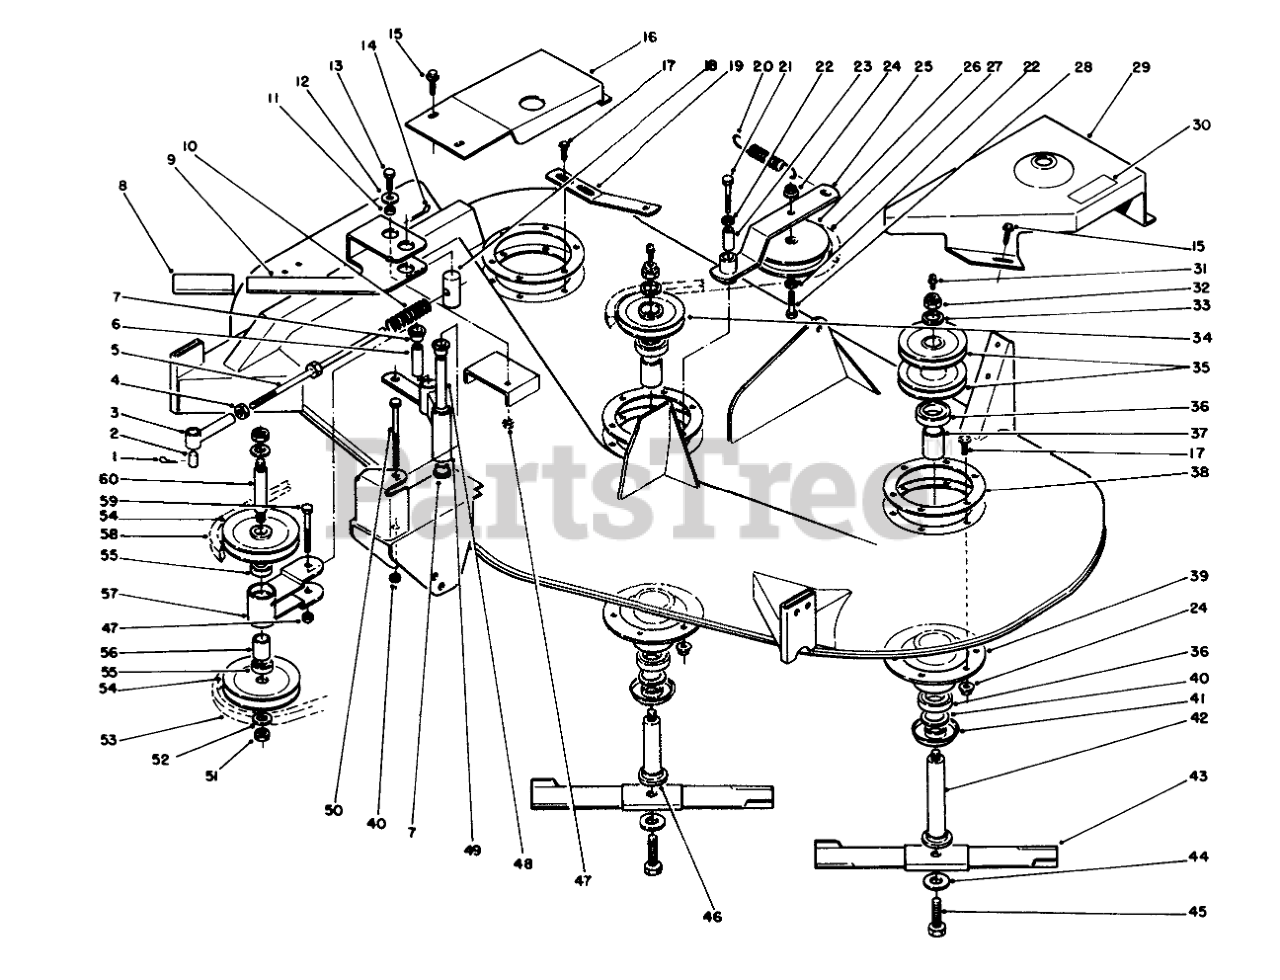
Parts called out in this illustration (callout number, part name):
2	PIN-CLEVIS
4	NUT-JAM
5	ROD-W.A. R
6	SPACER
7	BUSHING
9	Lever
10	SPRING-COMPRESSION
11	SPACER
12	Washer
13	BOLT
14	PIN-4
15	SCREW-HHFTF
16	Cover-Belt, R.H.
17	Bolt-Carriage
18	TRUNNION
19	Strap-Spring
20	SPRING-EXTENSION
21	Bolt
22	Washer
23	SLEEVE
24	NUT-HF
25	Arm-Idler
26	Pulley
27	V-BELT
28	BOLT
29	Cover-Belt L.H.
30	DECAL-HOC
31	FITTING-GREASE
32	Nut
33	Washer
34	PULLEY
35	PULLEY-L.H. R
36	BEARING-BALL
37	SPACER-BEARING
38	SUPPORT-DECK, RING
39	Housing-Spindle
40	WASHER-WHEEL
41	SHIELD-BEARING
42	SHAFT-SPINDLE
43	Blade
44	Washer
45	SCREW-BLADE
46	SHAFT-SPINDLE
47	NUT
48	SPACER
49	Arm Assembly
50	BOLT
51	Nut
52	Lockwasher
53	V-BELT
54	PULLEY R
55	BEARING-BALL
56	SPACER
57	Arm Assembly
58	V-BELT
59	COUNTER-SHAFT
60	Screw-Hex. Hd.
